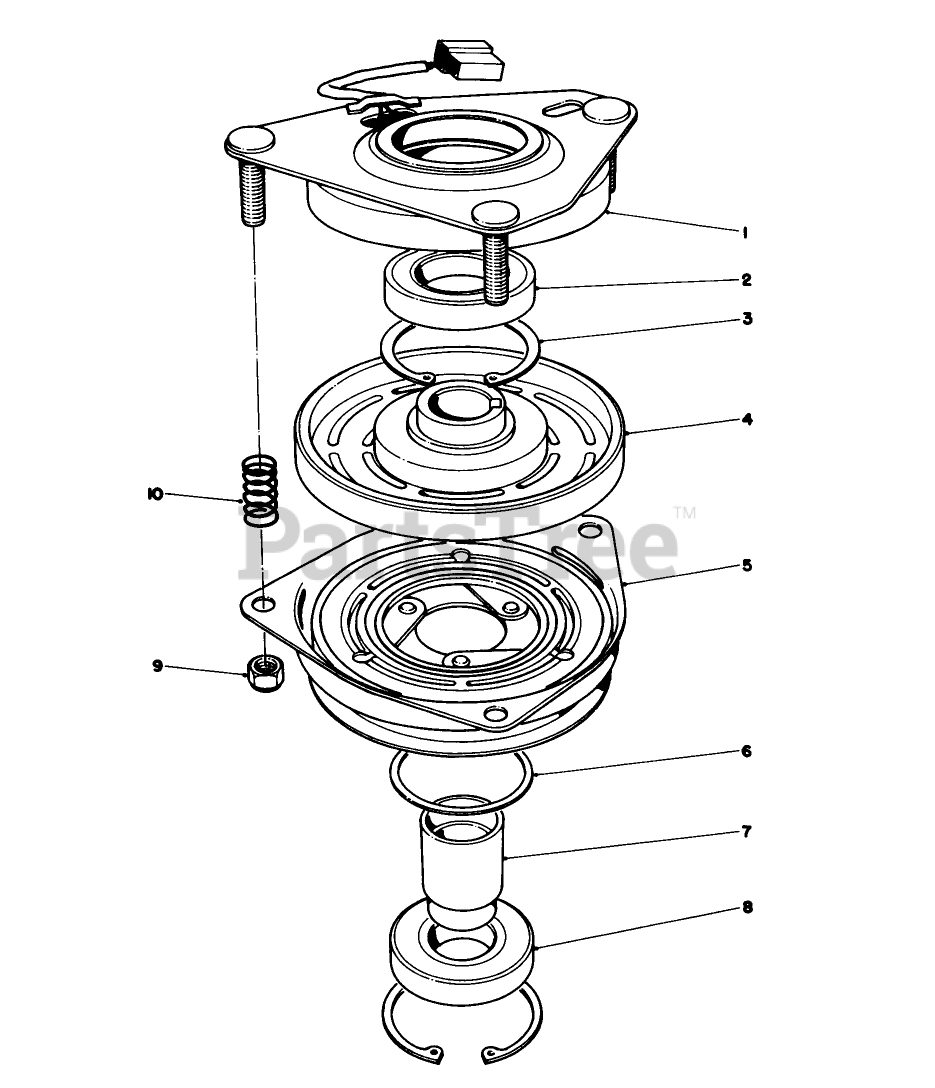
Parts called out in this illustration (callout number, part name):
1	FIELD BEARING ASM
2	BEARING-FIELD
3	RING-RETAINING
4	FIELD COIL/ROTOR BEARING ASM
6	SPACER-BEARING, PULLEY
7	COLLAR-BEARING
9	NUT-LOCK
10	SPRING
